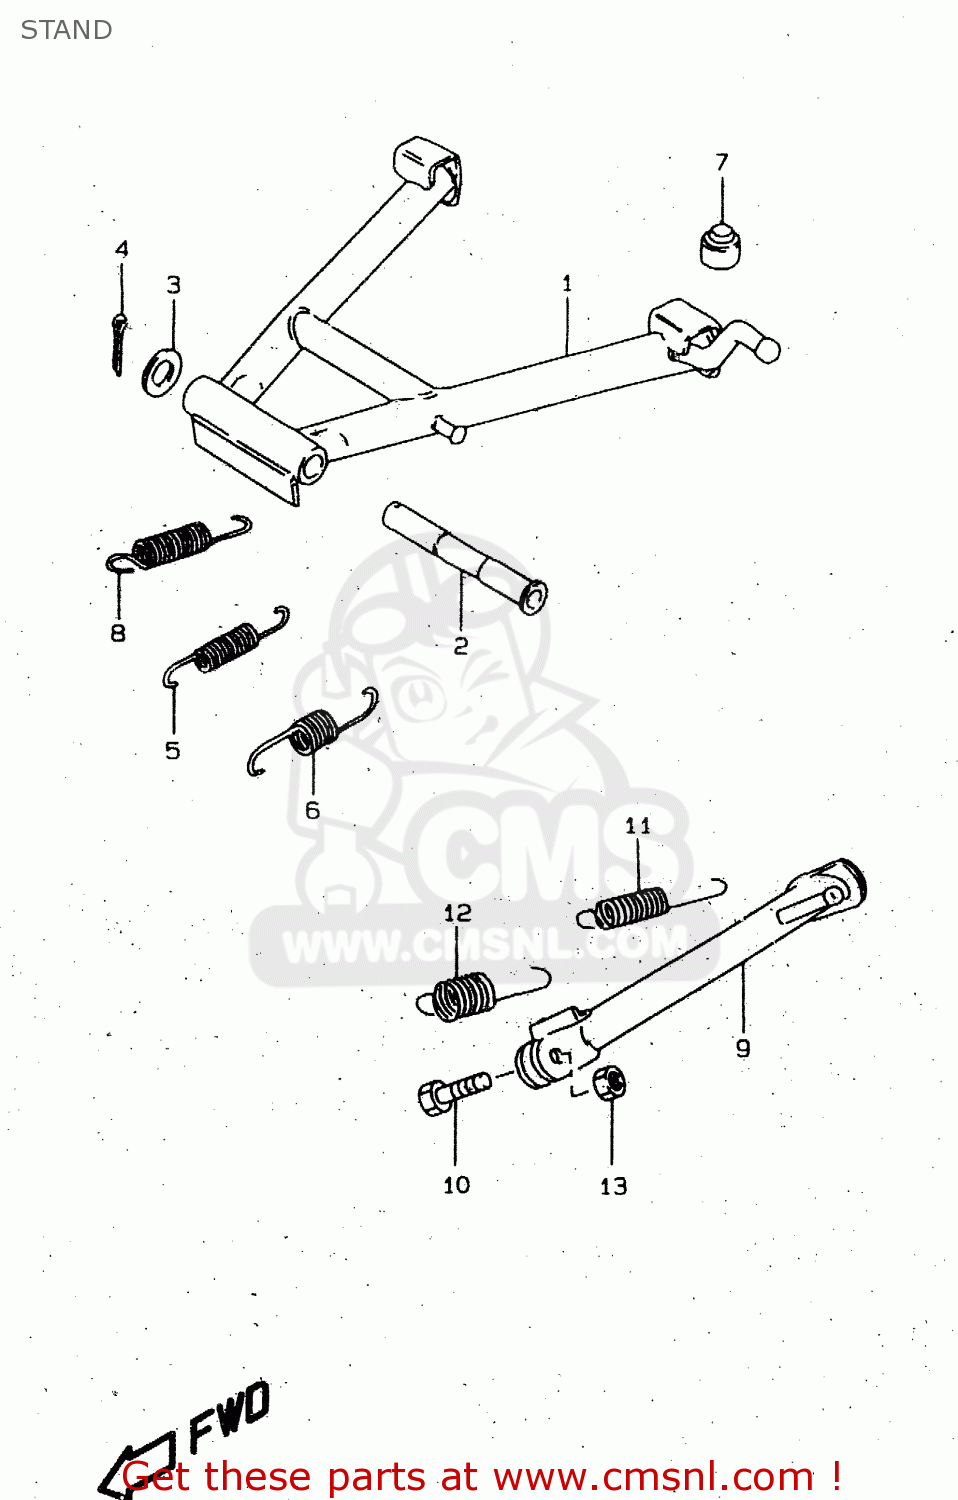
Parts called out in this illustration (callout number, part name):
1	STAND,CTR
2	SHAFT,CTR STAND
3	WASHER(16.2X30X2.6)
4	COTTER PIN
5	SPRING
6	SPRING
7	CUSHION
8	SPRING
9	STAND,PROP
10	BOLT(10X30)
11	SPRING
12	SPRING
13	NUT
